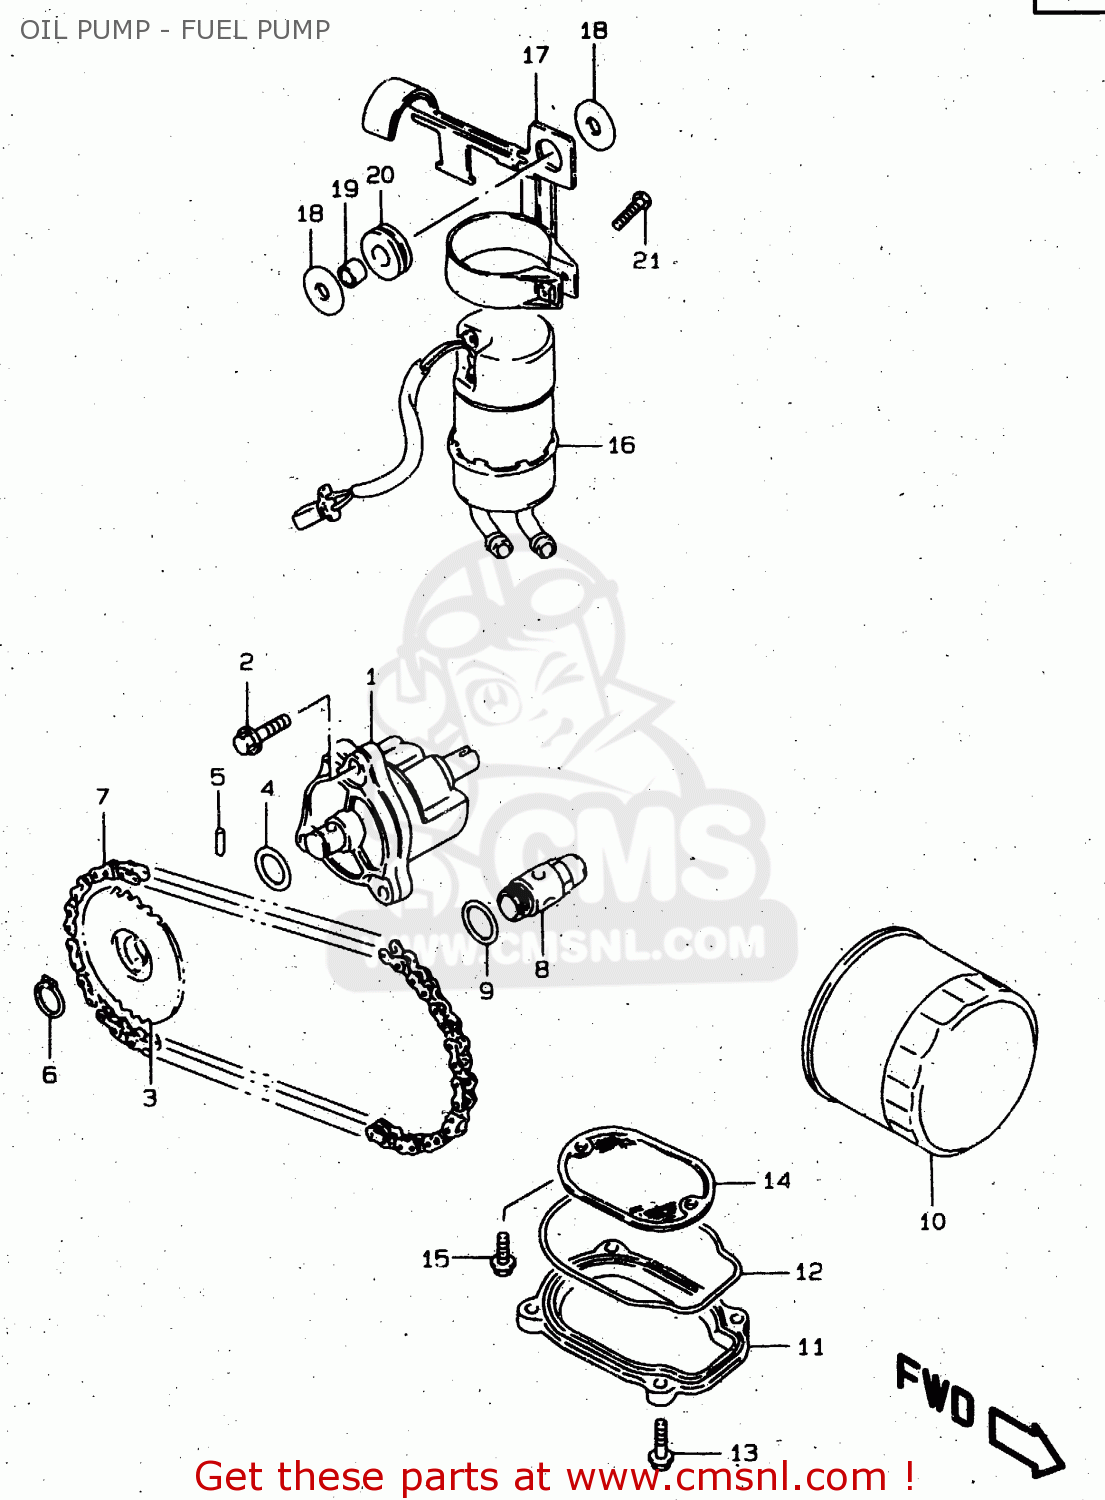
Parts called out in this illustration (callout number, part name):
1	PUMP ASSY,ENGINE OIL
2	BOLT
3	SPROCKET,OIL PUMP DRIVEN
4	SHIM(12X20X0.5)
5	PIN(5X18)
6	CIRCLIP,12 MM
7	CHAIN,OIL PUMP DRIVE
8	VALVE ASSY,OIL RELIEF
9	GASKET(16X22X2) (NAS)
10	FILTER ASSEMBLY,ENGINE OIL
11	CAP,OIL STRAINER
12	O RING,OIL STRAINER CAP
13	BOLT
14	STRAINER,ENGINE OIL
15	SCREW
16	PUMP ASSY,FUEL
17	BRACKET,FUEL PUMP
18	WASHER(6.5X24X1.6)
19	SPACER(6.5X10.5X6.5)
20	CUSHION
21	SCREW
